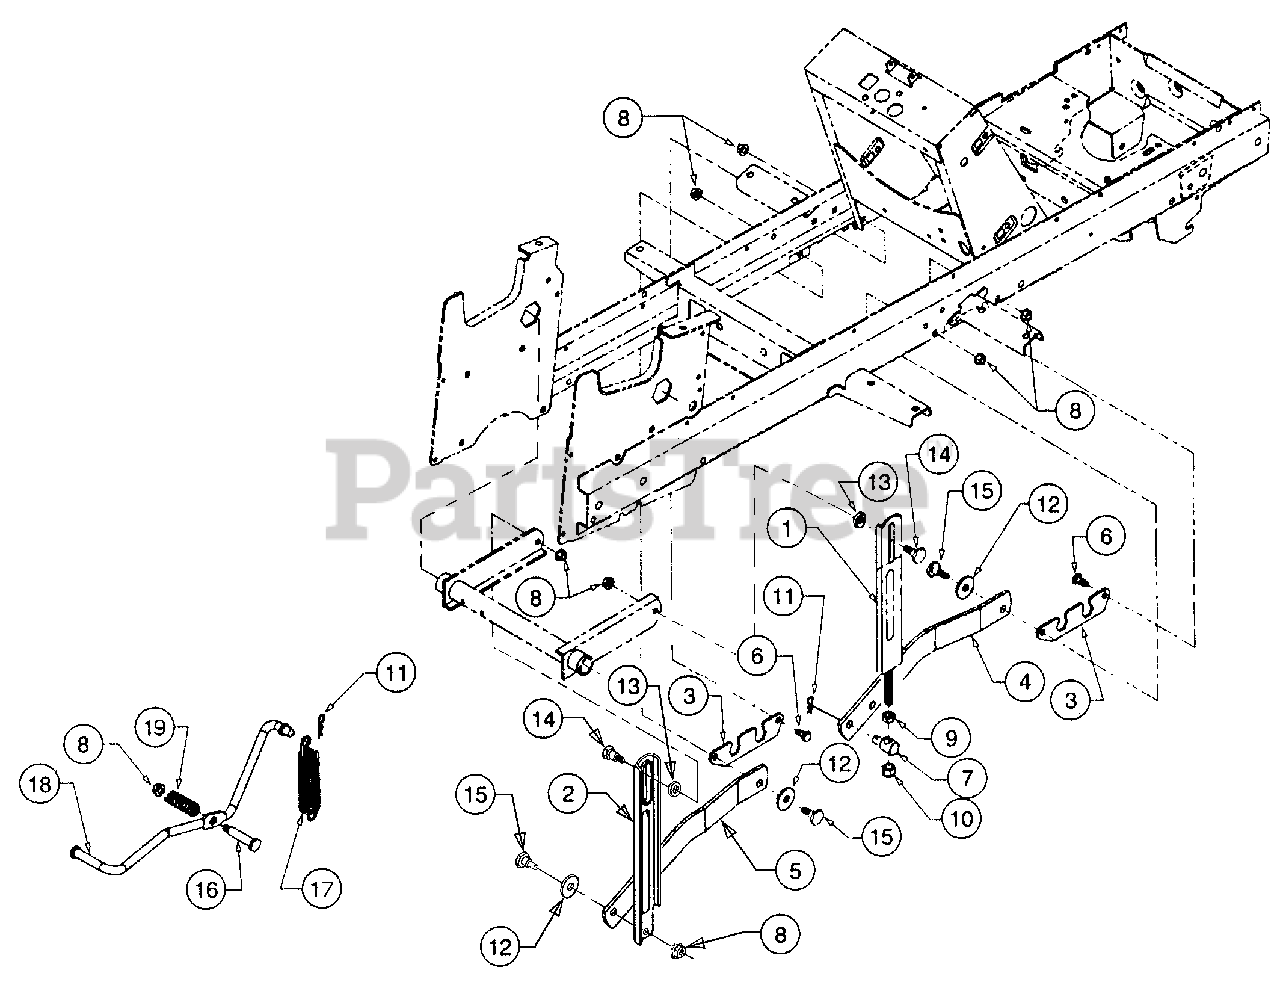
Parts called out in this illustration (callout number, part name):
7	Ferrule, Adjustment
8	Nut, Hex Flange Lock, 3/8-16
9	Nut, Hex Jam, 1/2-13 GR5
10	Nut, Hex Insert Lock, 1/2-13
11	Pin, Internal Cotter
12	Washer, Flat, .5 x 1.5 x .15
13	Washer, Flat, .531 x .875 x .15
14	Bolt, Shoulder
15	Bolt, Shoulder
16	Bolt, Shoulder
17	Spring, Ext., .91" OD x 7.33
18	Rod, RH Lift Assist
19	Spring, Compression, .63 ID x 2
